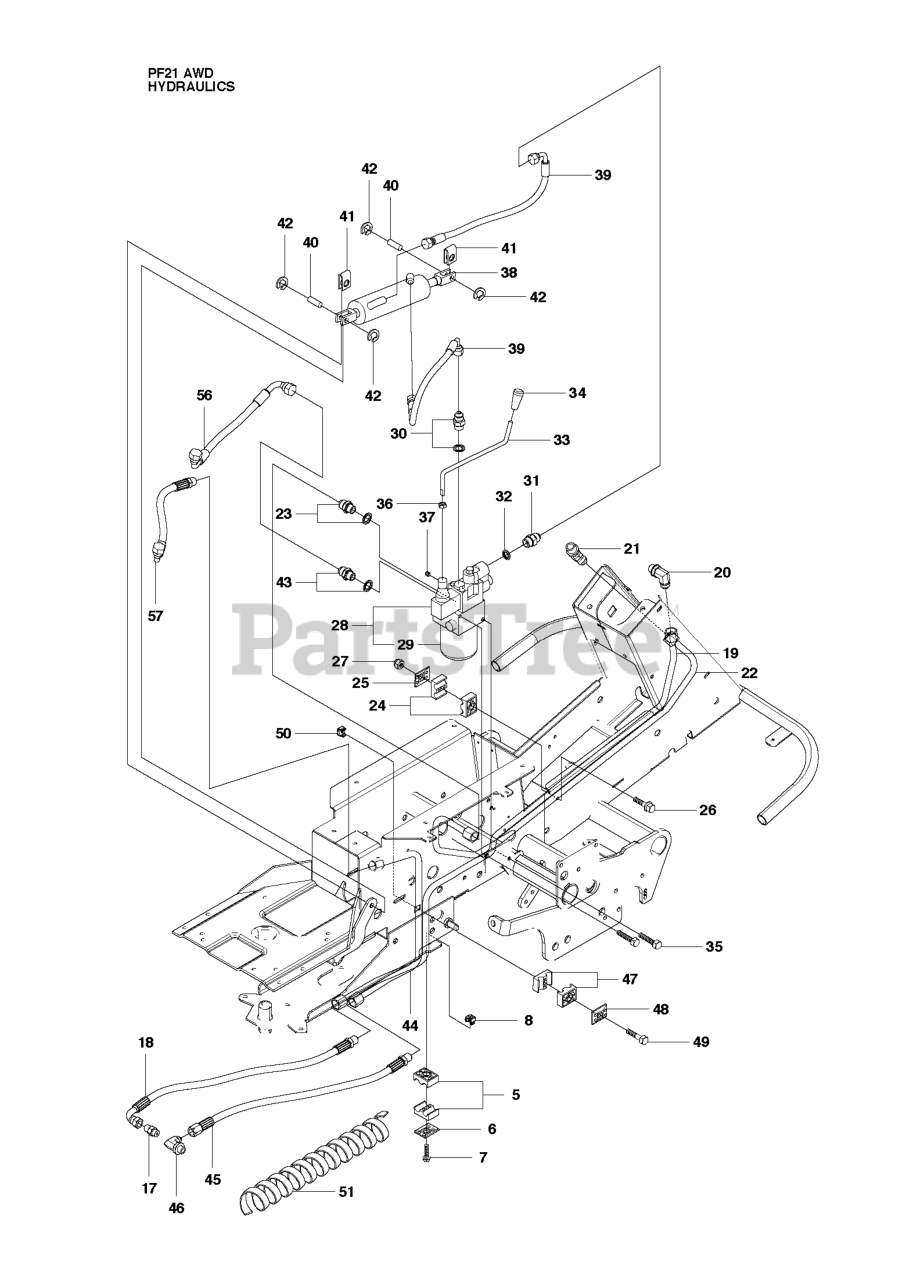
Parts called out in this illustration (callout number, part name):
5	PIPE CLAMP
6	COVER PLATE
7	SCREW EHHFM
24	PIPE CLAMP
27	LOCKNUT M6
29	FILTER
35	REPL BY 725 24 49-51
36	NUT
42	RETAINING RING SGA 10
47	PIPE CLAMP
51	HOSE GUARD
